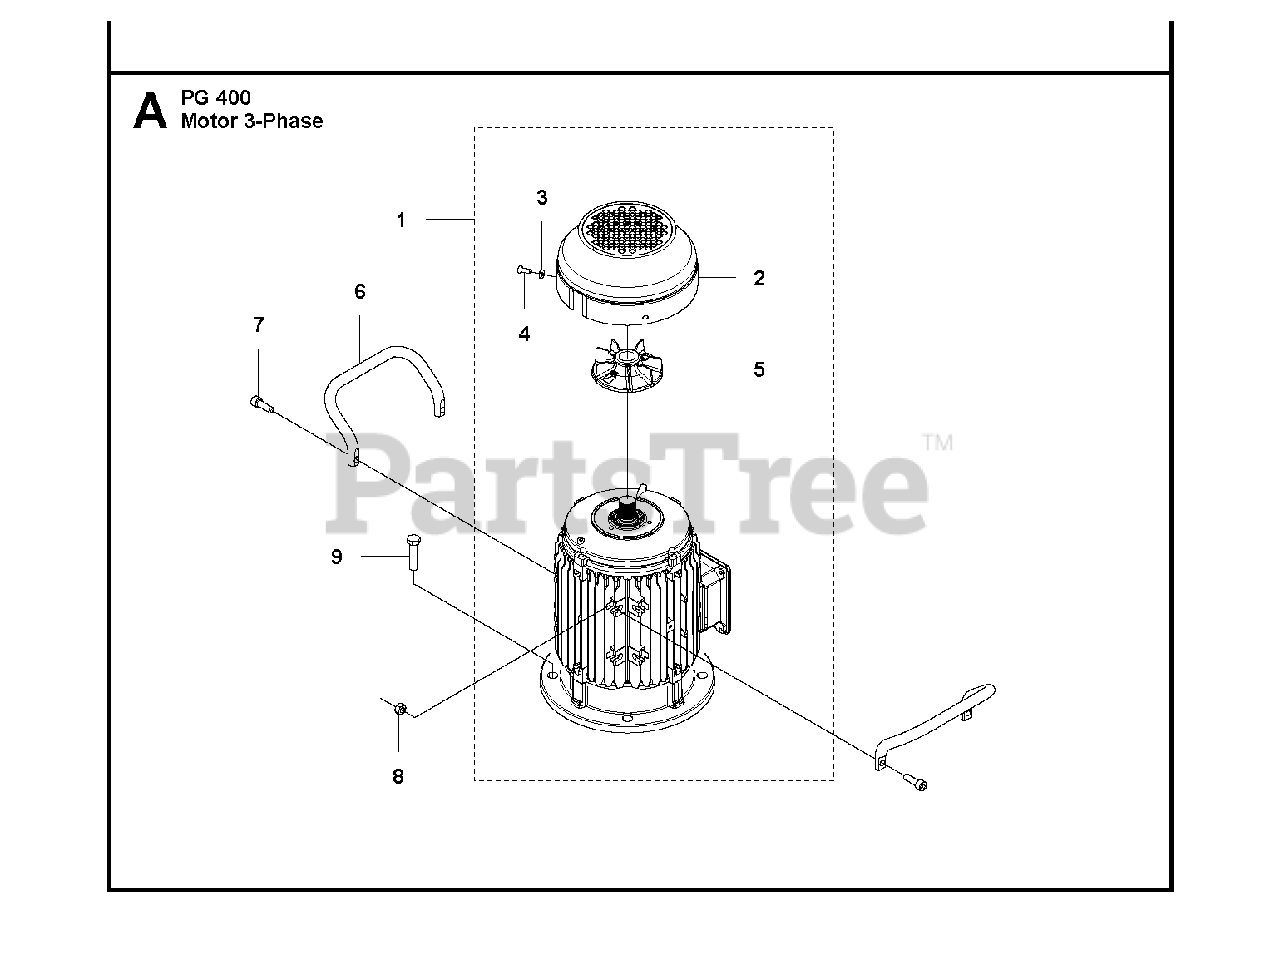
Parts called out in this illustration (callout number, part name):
1	MOTOR3 phase, 230/400V, 50/60Hz
3	WASHER
8	HEXAGON NUT
